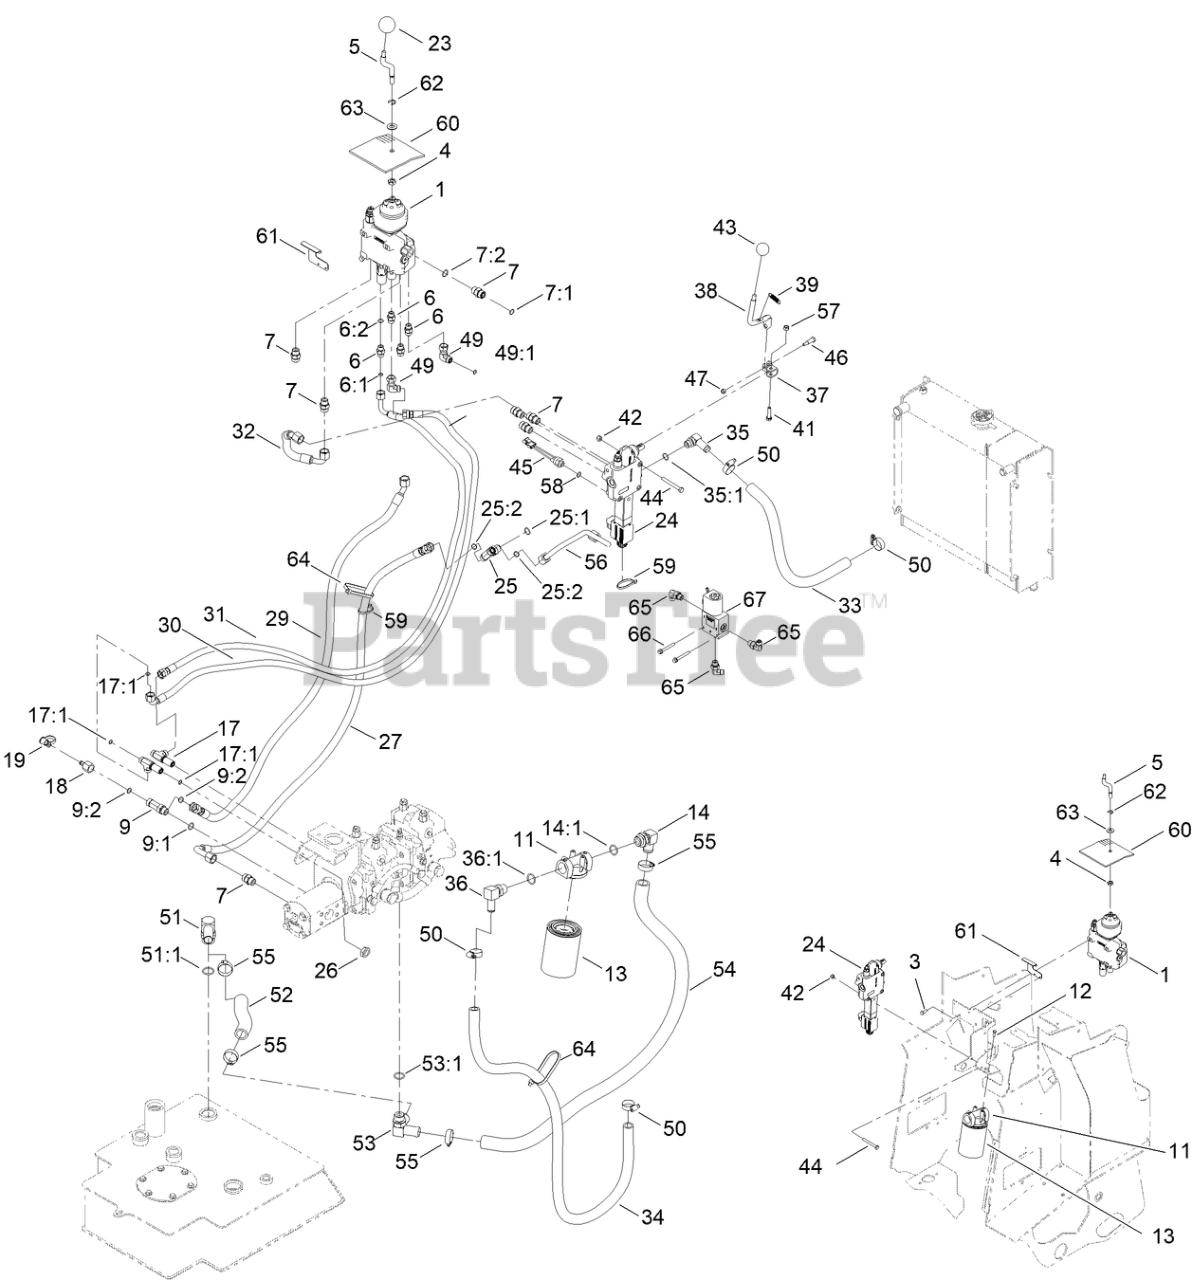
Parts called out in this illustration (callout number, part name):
1	2 SPOOL VALVE ASM
3	SCREW-HH
5	SHAFT-HANDLE, LIFT/TILT
6	FITTING-STRAIGHT
6:1	O-RING
6:2	O-RING
7	FITTING-STRAIGHT
7:1	O-RING
7:2	O-RING
9	FITTING-TEE
9:1	O-RING
9:2	O-RING
11	HEAD-FILTER
12	SCREW-HH
13	FILTER-OIL
14	FITTING-90
14:1	O-RING
17	FITTING-TEE, BULKHEAD
17:1	O-RING
18	FITTING
19	CAP-DUST
24	DOUBLE DETENT VALVE ASM
25	FITTING-HYD, TEE
25:1	O-RING
25:2	O-RING
26	NUT-LOCK
27	HYD HOSE ASM
29	HYD HOSE ASM
30	HYD HOSE ASM
31	HYD HOSE ASM
32	HYD HOSE ASM
33	HOSE-RETURN
34	HOSE-RETURN
35	FITTING-ELBOW, 90
35:1	O-RING
36	FITTING-ELBOW, 90
36:1	O-RING
37	BRACKET-AUXILARY
38	HANDLE ASM
39	SPRING-EXTENSION
41	SCREW-HH
42	NUT-LOCK, NI
44	SCREW-HH
45	SWITCH-BALL
46	BOLT-SHOULDER
47	NUT-LOCK, NI
49	FITTING-HYD, 90 DEG
49:1	O-RING
50	CLAMP-HOSE
51	FITTING-HYD, 90 DEG
51:1	O-RING
52	HOSE-SUCTION
53	CONNECTOR
53:1	O-RING
54	HOSE-RETURN
55	CLAMP-HOSE
56	HYDRAULIC TUBE ASM
57	NUT-LOCK, NI
58	O-RING
59	TIE-CABLE
60	DEFLECTOR-AIR
61	BRACKET-DEFLECTOR
62	RING-RETAINING
63	WASHER-PIVOT
65	FITTING-ELBOW, 90 DEG
66	SCREW-HHF
67	SOLENOID VALVE
